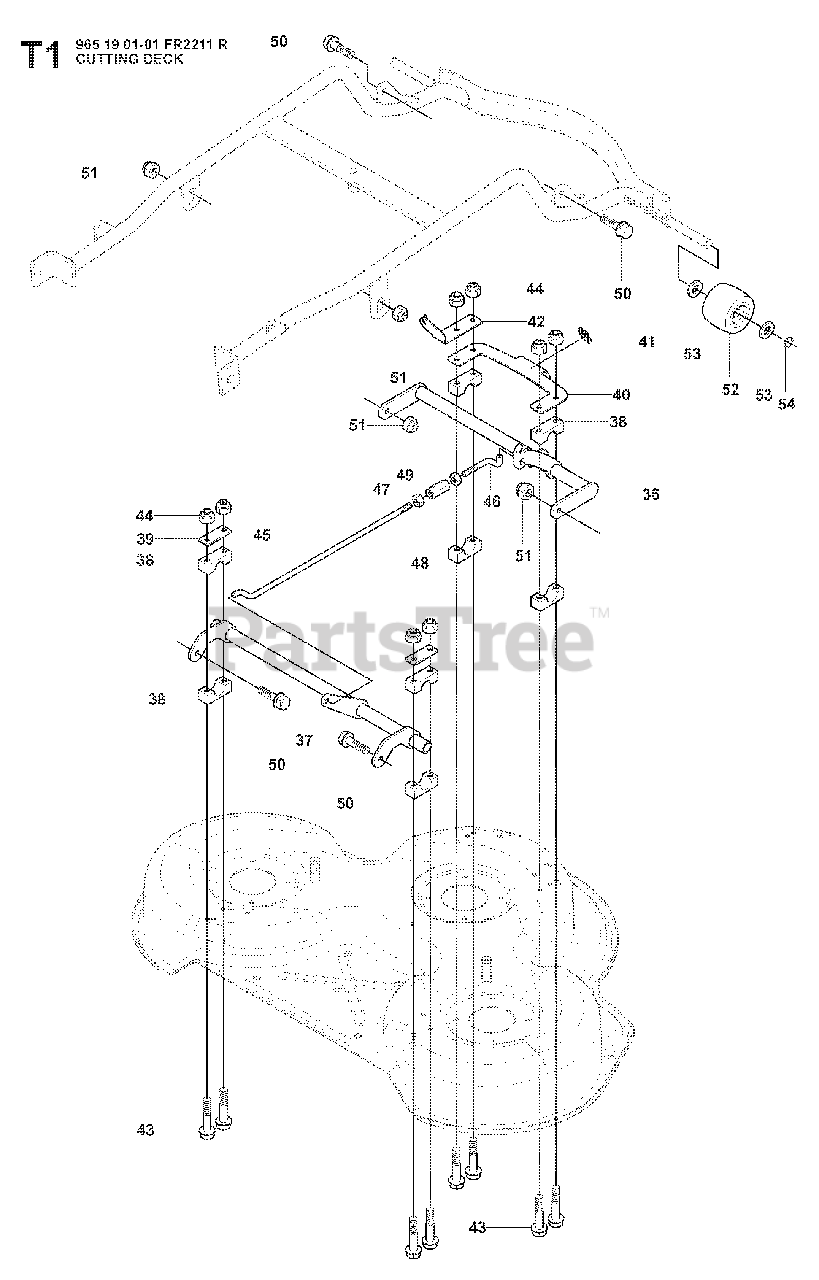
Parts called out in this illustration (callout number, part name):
44	LOCKNUT M8
51	LOCKNUT M8
52	DECK ROLLER, FRONT
54	RETAINING RING SGA 15
